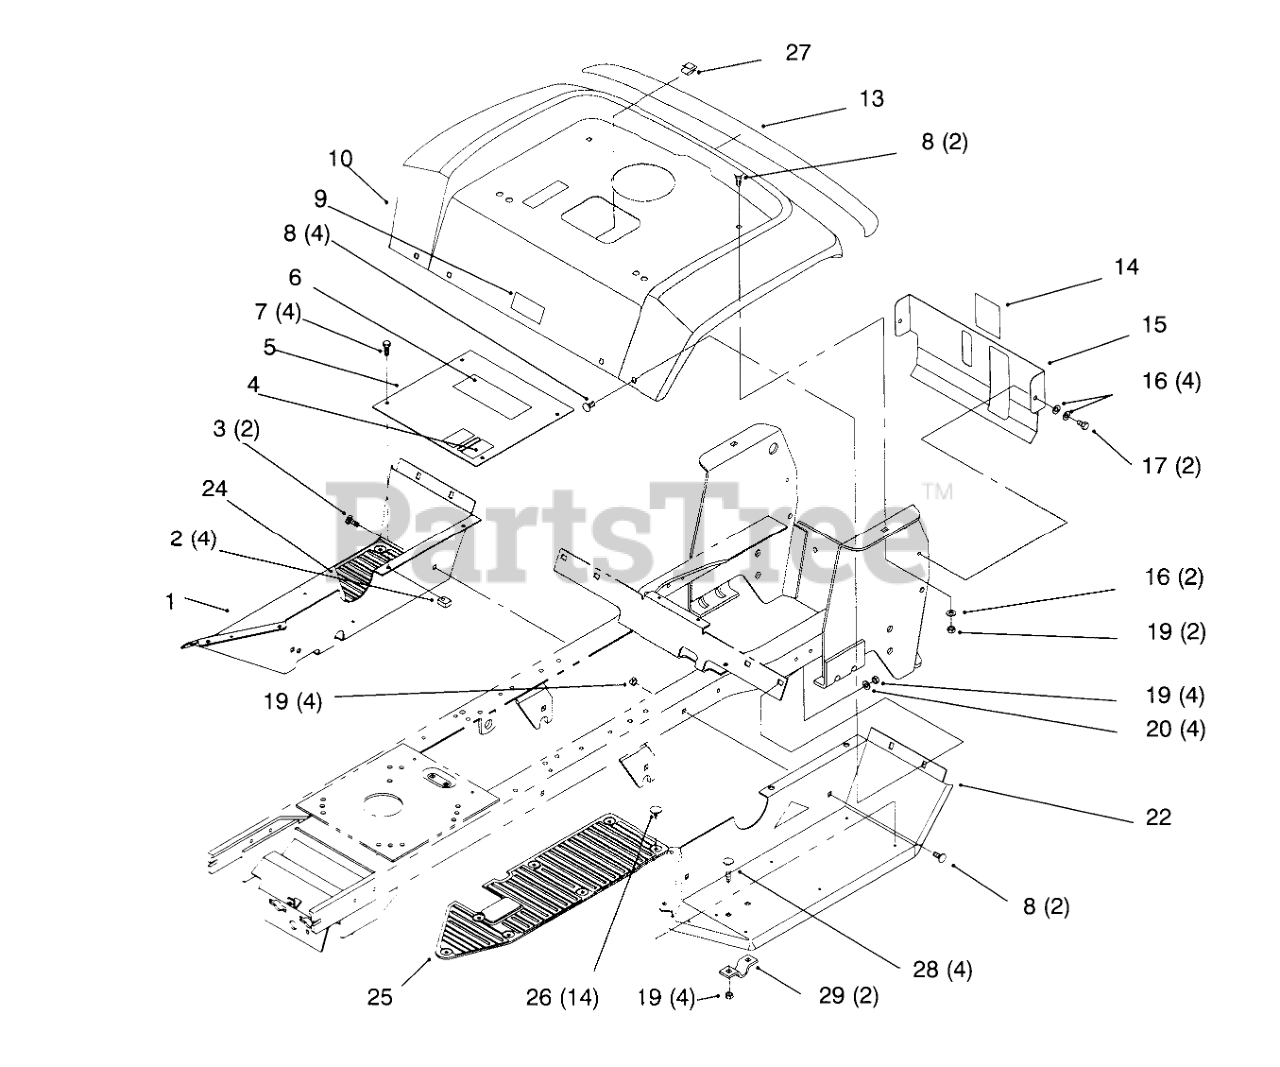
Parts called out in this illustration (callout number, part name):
1	Footrest-RH (Only On: 72042,72062)
1	Footrest-RH (Only On: 72043,72063,72103)
2	Nut-Retainer
3	SCREW-CARR
4	Decal-HOC (Only On: 72042,72043)
4	Decal-HOC (Only On: 72062,72063,72103)
5	PLT - FTREST W/DECAL
6	DECAL-DANGER
7	SCREW-HH
8	BOLT-CARR
9	Decal-USA (Only On: 72042,72043)
13	DECAL - REAR FENDER
14	DECAL-LEVEL, FUEL
15	COVER-REAR
16	WASHER-PLAIN
17	SCREW
19	NUT-LOCK, NI
20	WASHER-FLAT
22	Footrest-LH (Only On: 72042,72062)
22	Footrest-LH (Only On: 72043,72063,72103)
24	Mat-Foot RH (Only On: 72043,72063,72103)
24	Mat-Foot RH (Only On: 72042,72062)
25	Mat-Foot LH (Only On: 72043,72063,72103)
25	Mat-Foot LH (Only On: 72042,72062)
26	FASTENER-PANEL
27	CLIP-RETAINER, WIRE
28	SCREW-CARR
29	CLAMP
